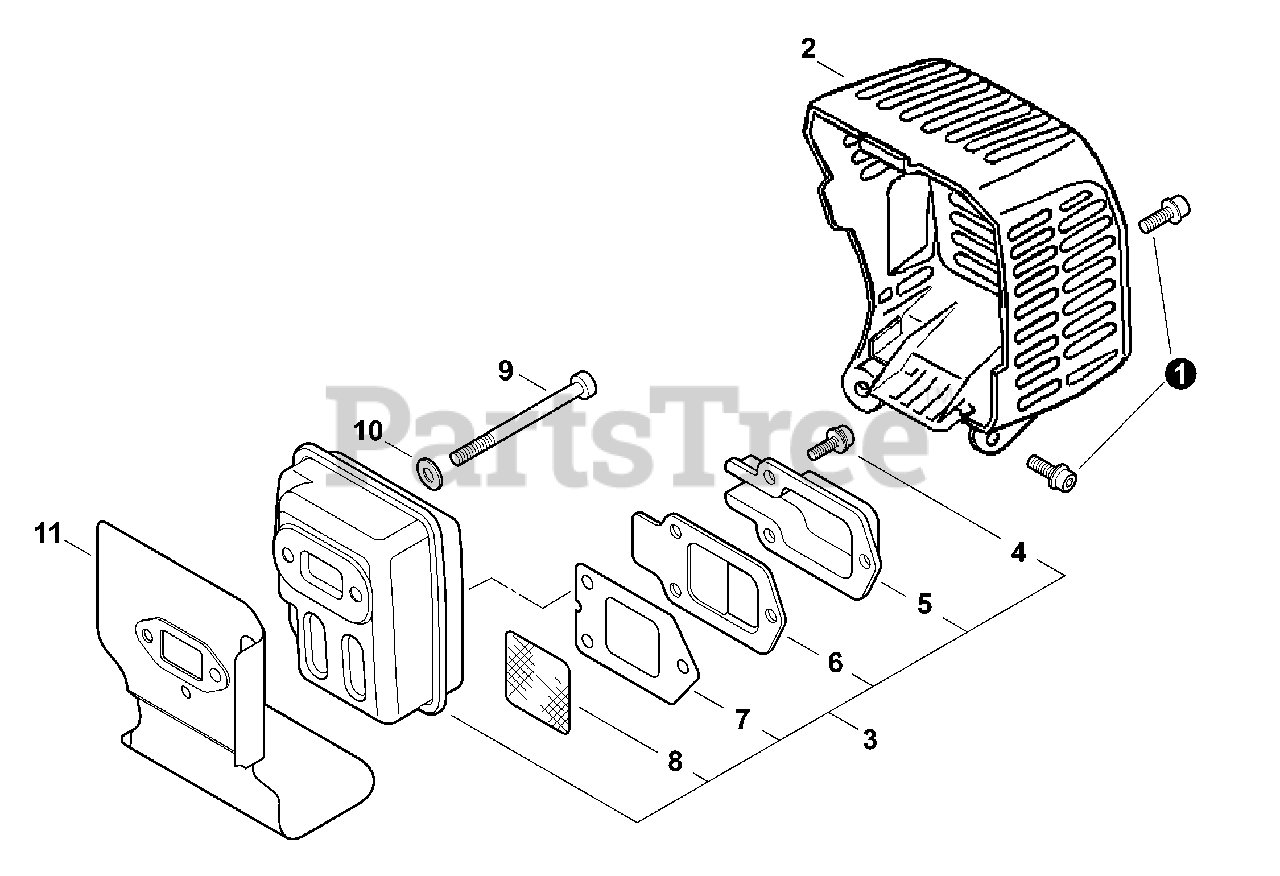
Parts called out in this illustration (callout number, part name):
1	COVER, MUFFLER
2	BOLT 5×12
3	MUFFLER ASSY
4	SCREW 4×10
5	GUIDE, EXHAUST
6	GUIDE, EXHAUST
7	GASKET, EXHAUST
8	SCREEN, SPARK ARRESTER
9	BOLT 5×55
10	WASHER 5.3×10×1
11	HEAT SHIELD, EXHAUST
